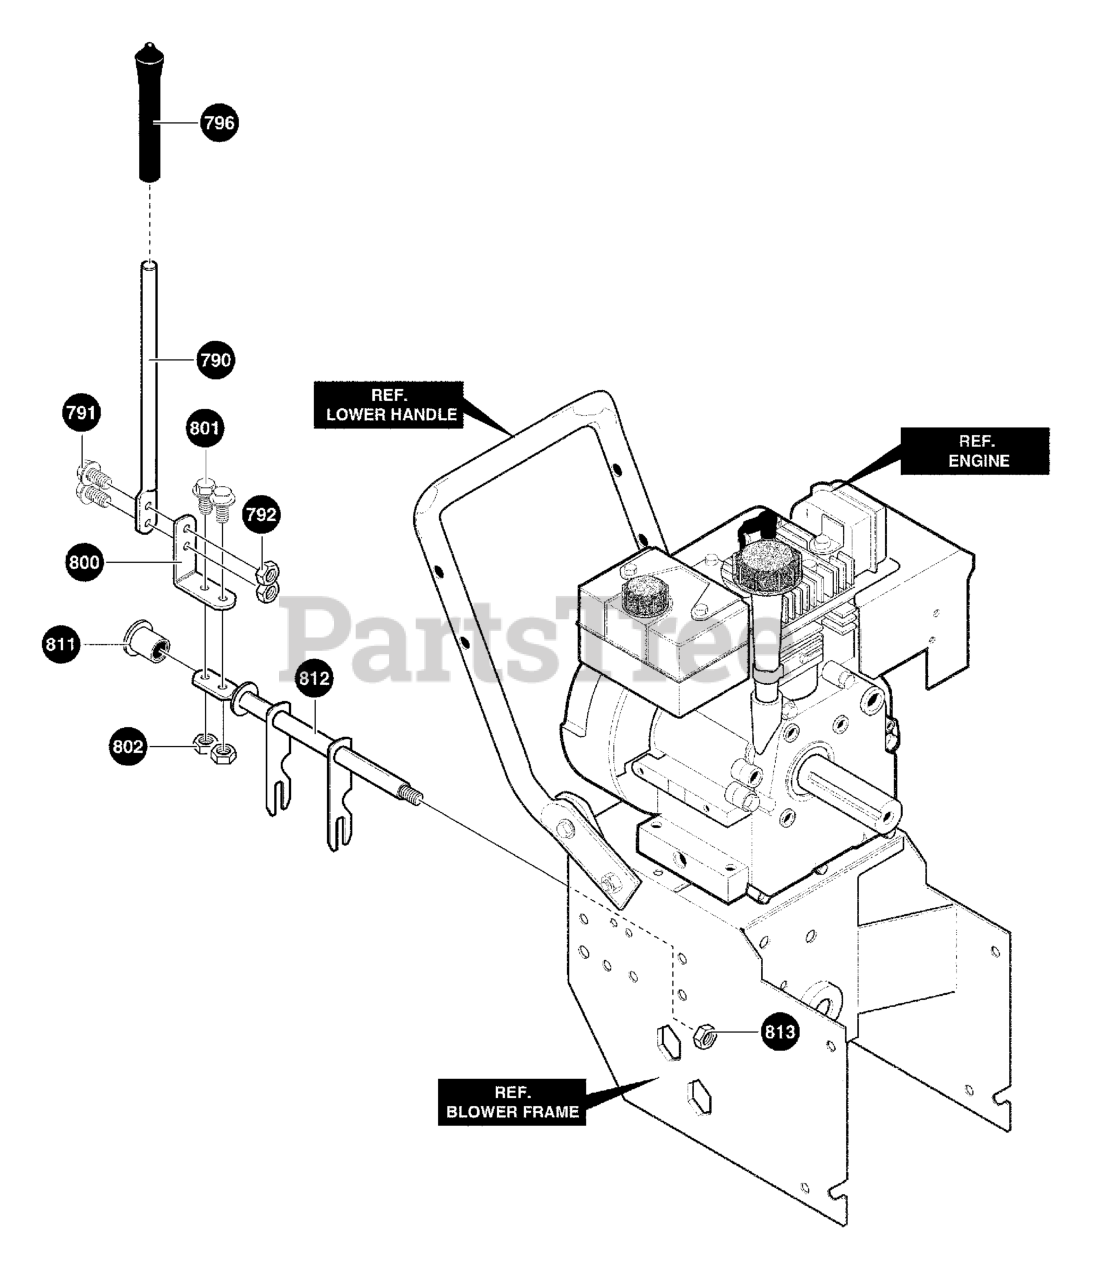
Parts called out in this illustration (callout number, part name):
790	ROD, SHIFT
791	SCREW, 1/4-20X.75
792	NUT, 1/4-20 REGHEXCTRLK
796	KNOB, SLIP
800	LEVER, SPRING
801	SCREW, 1/4-20X.75
802	NUT, 1/4-20 REGHEXCTRLK
811	BEARING, FLANGED
812	ROD, ASSY. YOKE
813	NUT, 3/8-16 HEXCTRLK
